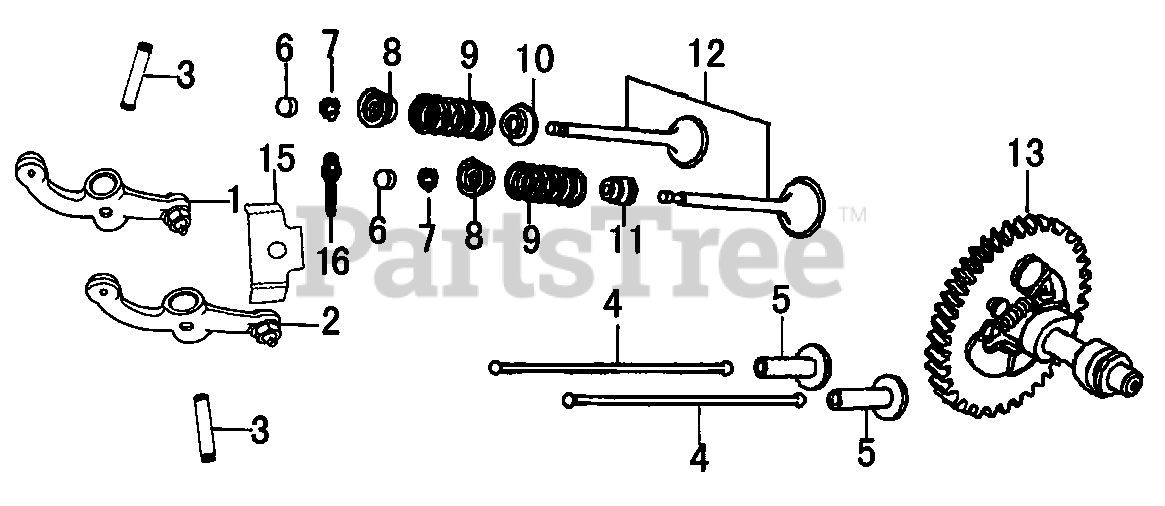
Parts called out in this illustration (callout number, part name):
1	ROCKER ARM ASSY.
2	ROCKER ARM ASSY.
3	VALVE ROCKER SHAFT
5	LIFTER , VALVE
6	ROTATOR,VALVE
7	LOCKER,VALVE
8	RETAINER,VALVE SPRING
9	SPRING,VALVE
10	SEAT,VALVE SPRING
11	SEAL,VALVE STEM
12	VALVE ASSY.
13	CAMSHAFT ASSY
15	RETAINER,ROCKER ARM SHAFT
16	BOLT,FLANGE 6x12
